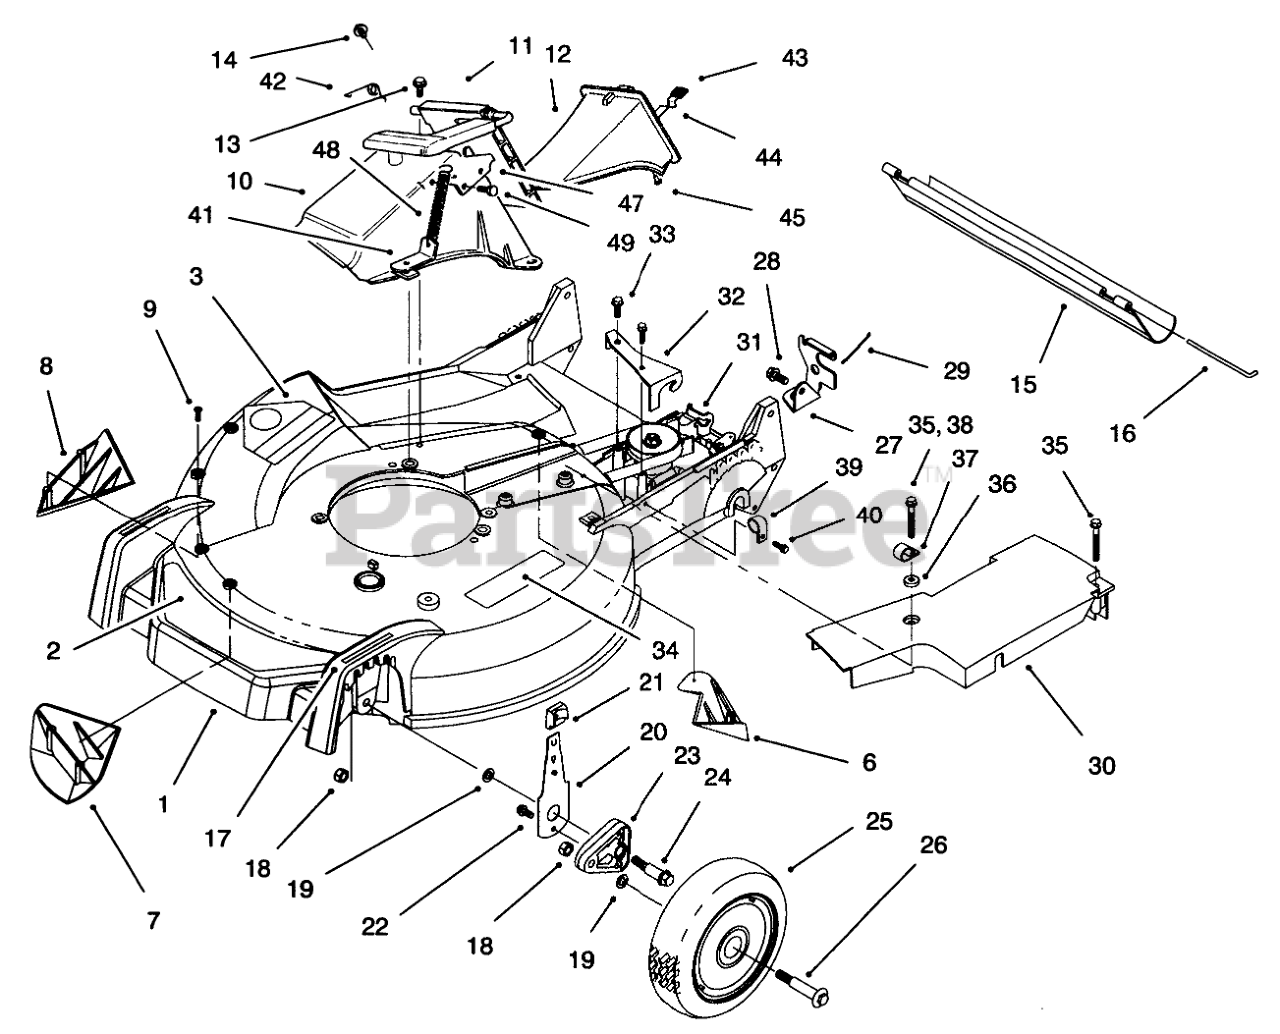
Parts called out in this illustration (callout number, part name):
1	Housing-21" (Incl. Ref. #3, 6-9 pg. 1 & 34 pg. 2)
2	DECAL - DECK
3	DECAL-DANGER
6	KICKER-REAR
7	KICKER-FRONT
8	KICKER-RH
9	SCREW-PPH
10	DISCHARGE TUNNEL
11	DISCHARGE DOOR ASM
12	Plug-Discharge (Incl. Ref. #43-45)
13	SCREW-HWH
14	SCREW AND WASHER ASM
15	SHIELD-TRAILING
16	ROD-SHIELD
17	DECAL - HOC
18	NUT-LOCK
19	WASHER
20	FRONT SPRING ARM ASM
21	KNOB-ARM
22	SCREW-HWH
23	ARM-PIVOT, FRONT
24	BOLT-SHOULDER
25	WHEEL AND TIRE ASM
26	BOLT-WHEEL
27	Bracket-Adj. Trac
28	SCREW-HWHTF
29	RETAINER-CABLE
30	COVER - BELT
31	GEARCASE ASM
32	Bracket-Guide
33	SCREW-HWHTF
34	DECAL-WARNING
35	SCREW-HHFTF
36	WASHER
37	CLAMP-CABLE
38	SCREW-SPECIAL
39	CLAMP-CABLE
40	SCREW-HWH
41	BRACKET-SPRING
42	RETAINER-DOOR
43	GRIP-LATCH
44	LATCH-PLUG, DISCHARGE
45	RIVET-HEAD, FLAT
47	LATCH-PLATE
48	SPRING-DOOR
49	SCREW-PLASTITE
